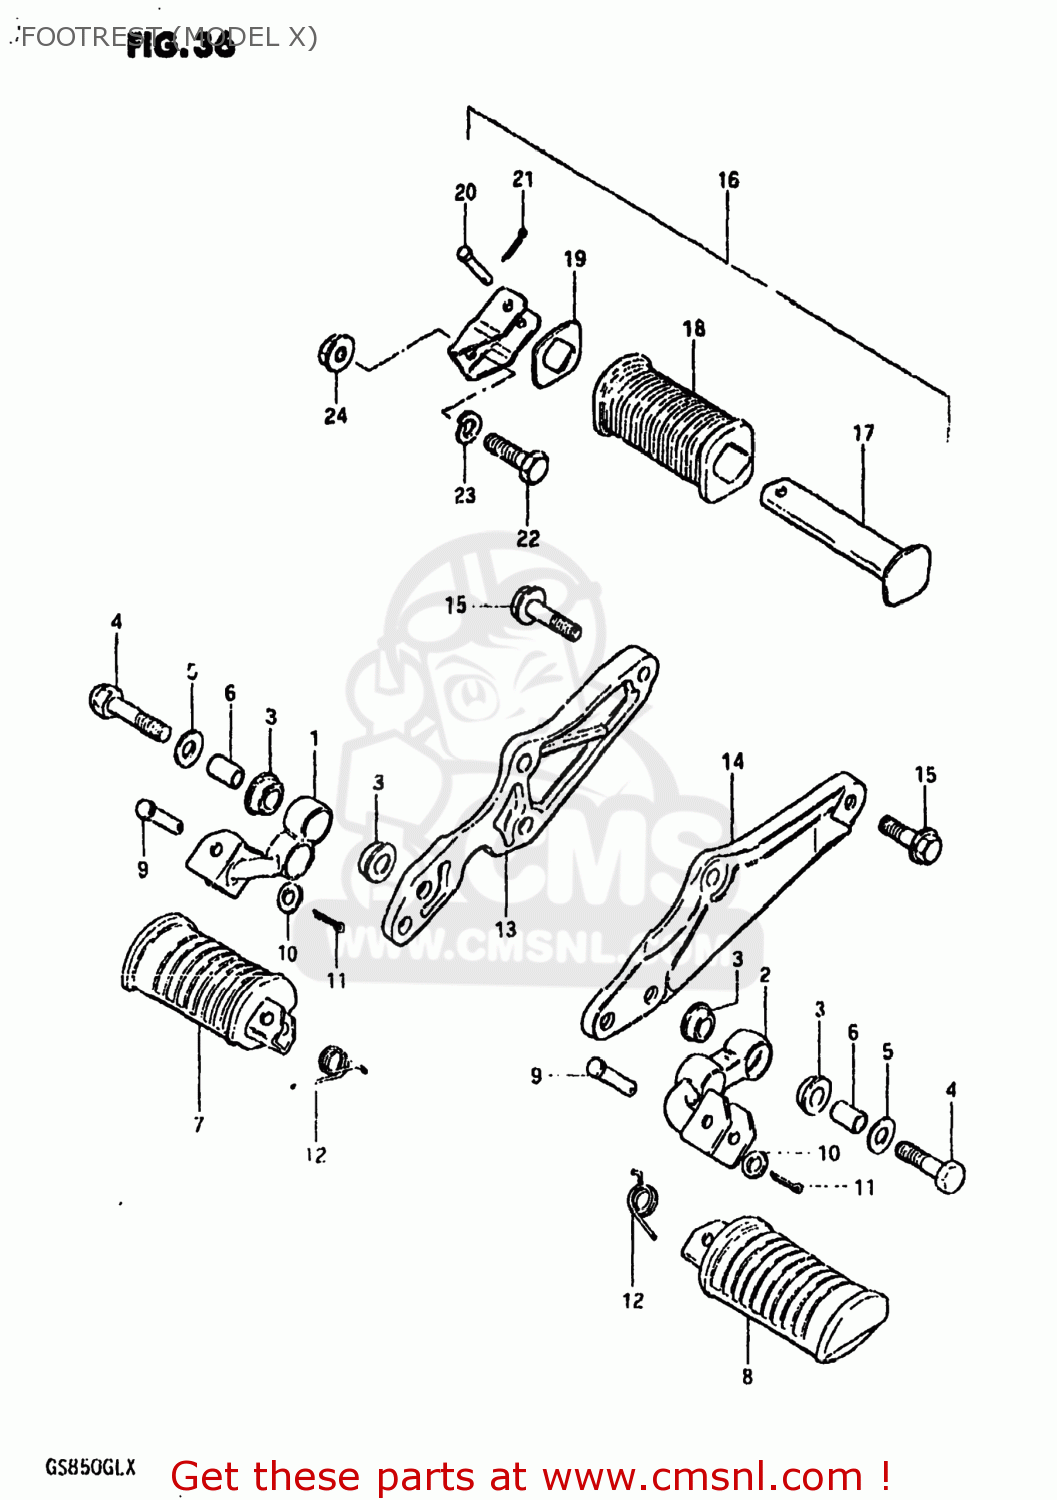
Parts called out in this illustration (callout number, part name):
1	BAR,FRONT FOOTREST
2	BAR,FRONT FOOTREST,LEFT
3	BUSH
4	BOLT(10X50)
5	WASHER(10.5X28X2.3)
6	SPACER (10.2X14X20)
7	RUBBER,FRONT FOOTREST
8	FOOTREST
9	PIN
10	WASHER
11	PIN
12	SPRING
13	BRACKET
14	BRACKET
15	BOLT
16	FOOTREST ASSEMBLY,PILLION
17	BAR,REAR FOOTREST,LEFT
18	RUBBER,PILLION FOOTREST
19	WASHER,FOOTREST RUBBER
20	PIN
21	PIN
22	BOLT,M10X1.25X
23	LOCK WASHER
24	NUT
